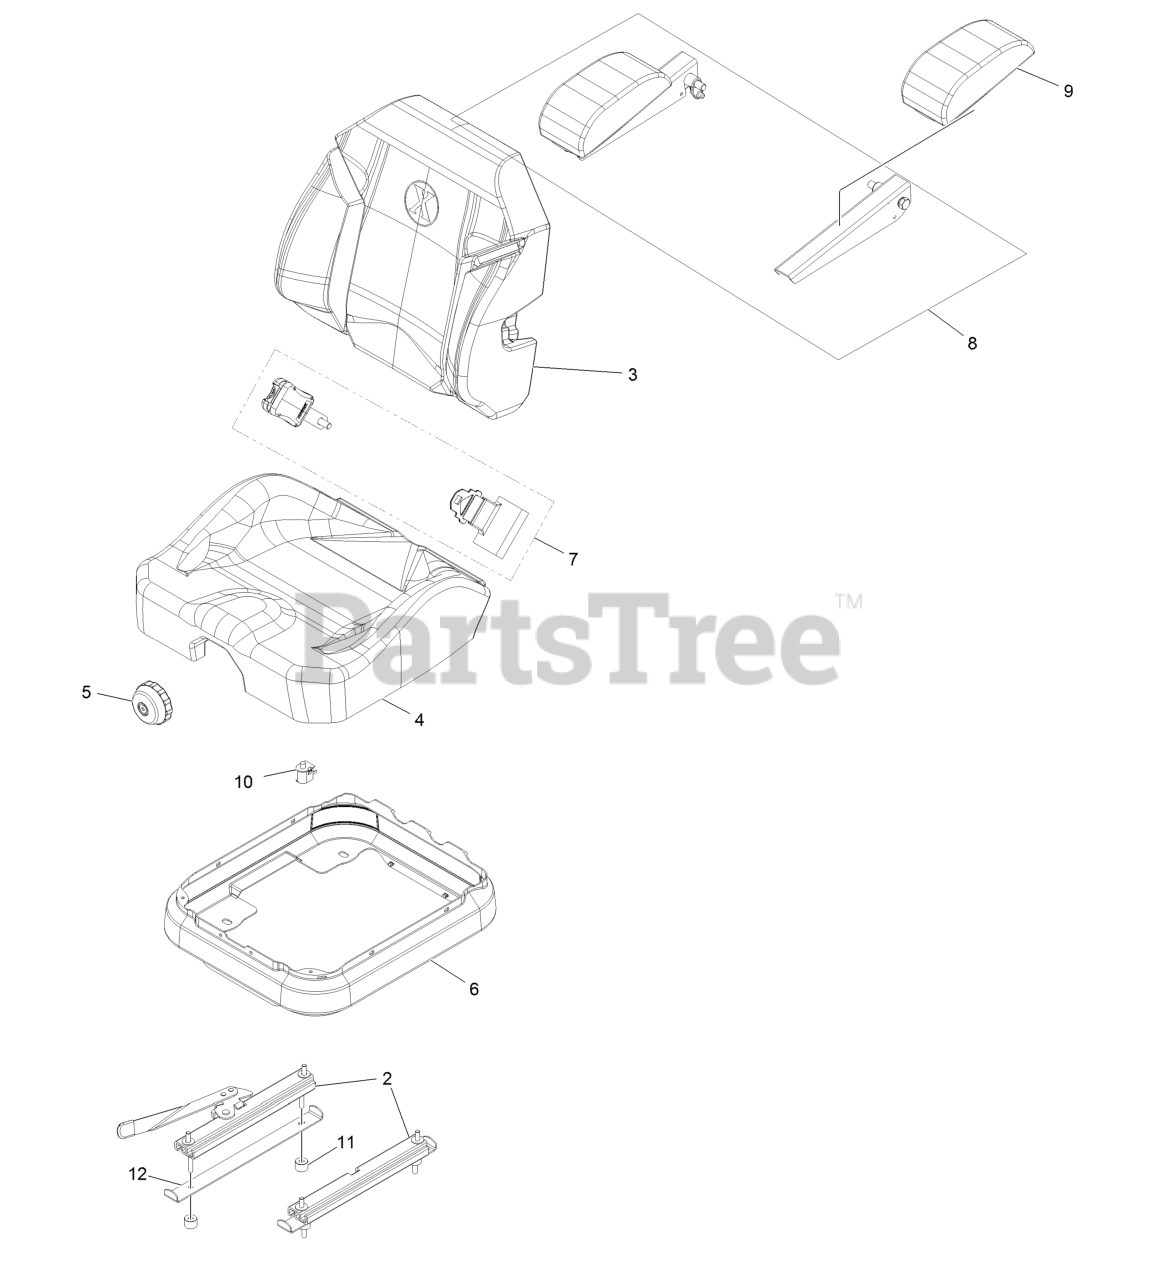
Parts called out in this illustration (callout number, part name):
2	SEAT TRACK SET
3	COVER-BACK 311463VN500
4	COVER-CUSHION 311464VN500
5	KNOB-ADJUSTER
6	COVER-SUSPENSION, BELLOWS
7	SEAT BELT SERVICE KIT
8	KIT-ARM REST SET
9	KIT-ARM REST PADS
10	SWITCH-BAIL
12	STOP, SEAT
